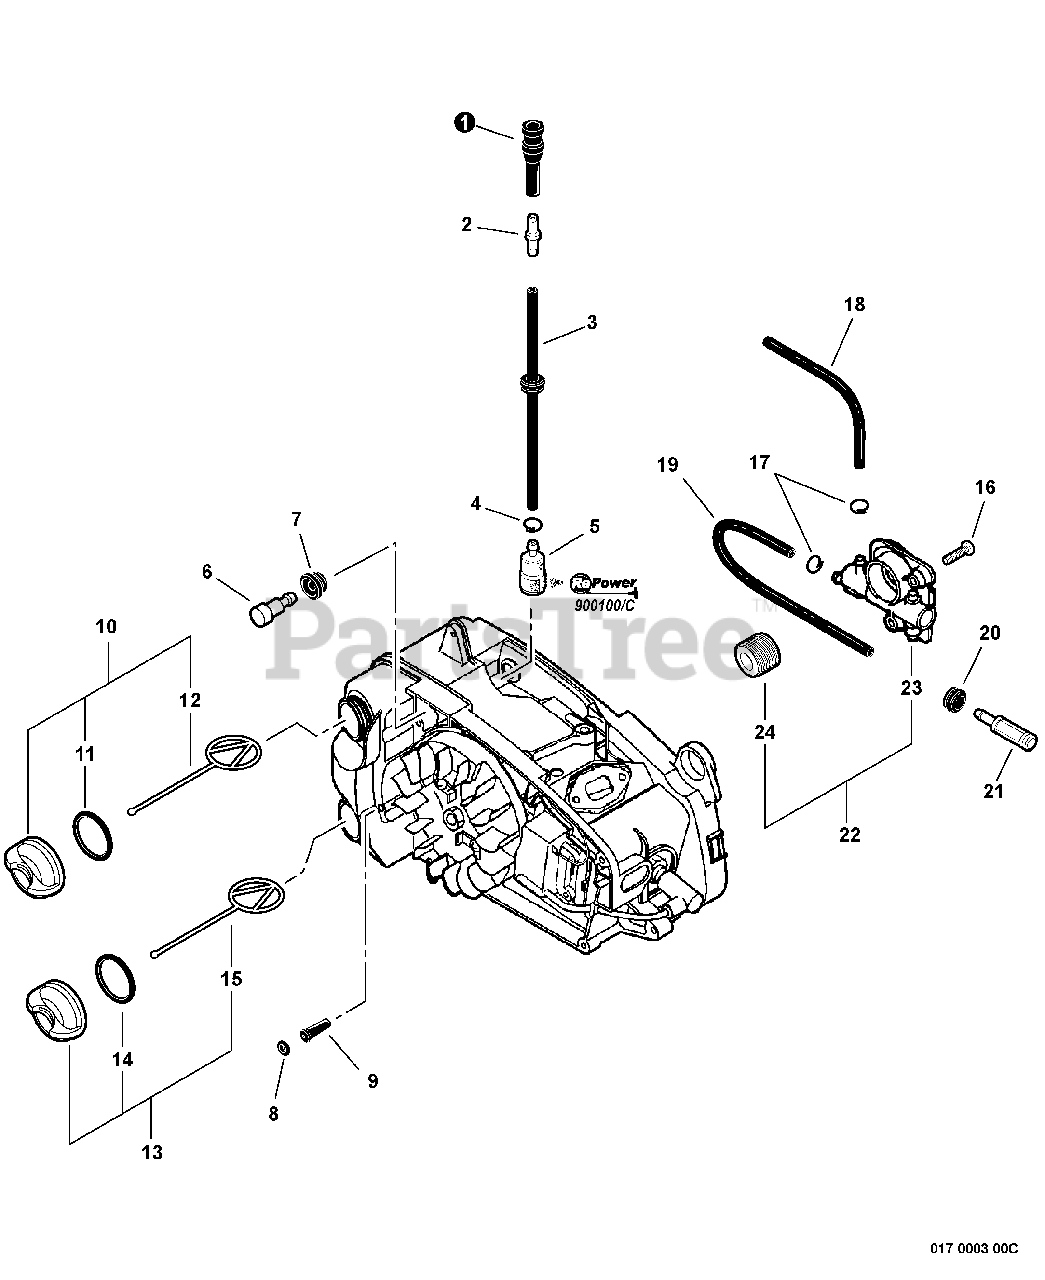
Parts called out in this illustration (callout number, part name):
1	PIPE, FUEL
2	CONNECTOR, PIPE
3	PIPE ASSY, FUEL
4	CLIP 6 MM
5	FILTER, FUEL
6	VENT ASSY
7	GROMMET, FUEL
8	O-RING S-4
9	VENT ASSY
10	CAP ASSY
11	O-RING 18
12	CONNECTOR, CAP L= 60 MM
13	CAP ASSY - BLACK
14	O-RING 18
15	CONNECTOR, CAP L= 60 MM
16	SCREW 4×12
17	CLIP Ø6.5 MM
18	PIPE 3×6×90 MM
19	PIPE 3×6×185 MM BLACK
20	GROMMET
21	FILTER, OIL
22	AUTO-OILER KIT
23	AUTO-OILER ASSY
24	GEAR, WORM
25	REPOWER TUNE-UP KIT
